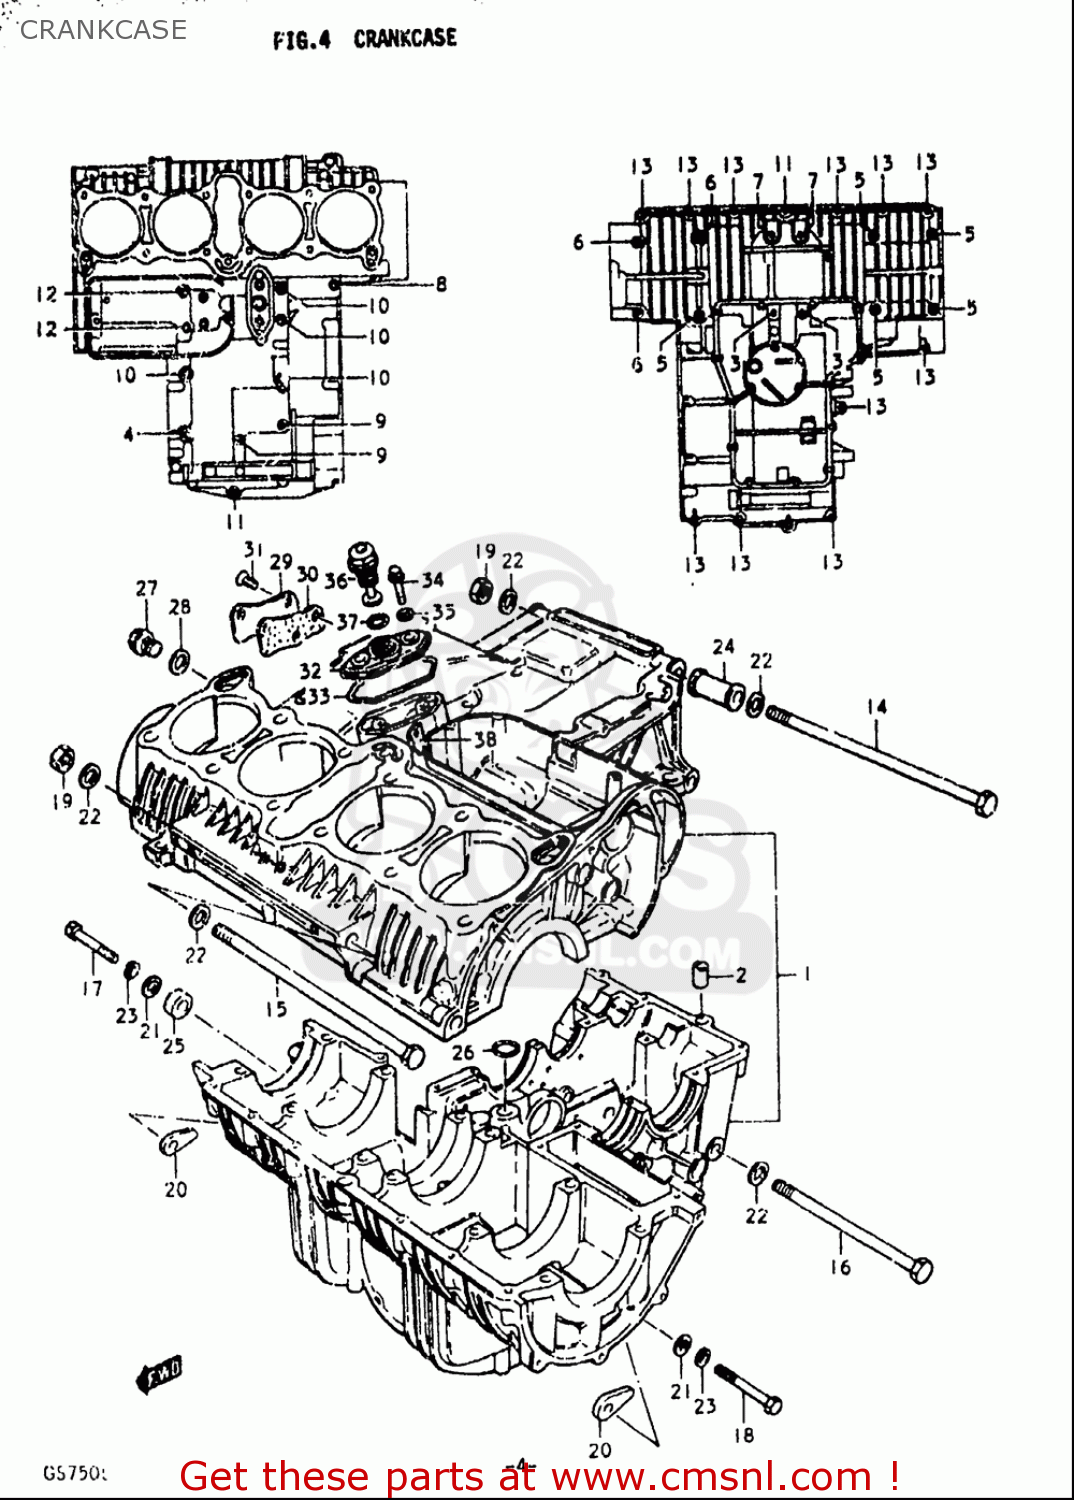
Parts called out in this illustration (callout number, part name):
2	PIN
3	BOLT(8X125)
4	BOLT
5	BOLT
6	BOLT
7	BOLT
9	BOLT
10	BOLT
11	BOLT
12	BOLT
13	BOLT
14	BOLT 10X250
15	BOLT 10X235
16	BOLT(10X165)
17	BOLT
18	BOLT
19	NUT
20	NUT
21	WASHER(10.5X20X3.2)
22	WASHER
23	WASHER,LOCK
24	SPACER,ENGINE MOUNT(L:50)
26	O RING(D:3.2,ID:12.9)
27	PLUG(14X12)
28	GASKET(14X19.2X2) (NAS)
29	CAP,OIL GALLERY
30	GASKET,OIL GALLERY CAP (NAS)
31	SCREW
32	HOUSING,OIL PRESSURE SWITCH
33	O RING,PRESSURE SWITCH HOUSING
34	BOLT
35	GASKET(5.8X13X1.2) (NAS)
36	SWITCH ASSY,OIL PRESSURE
37	O RING(D:1.9,ID:18.8)
